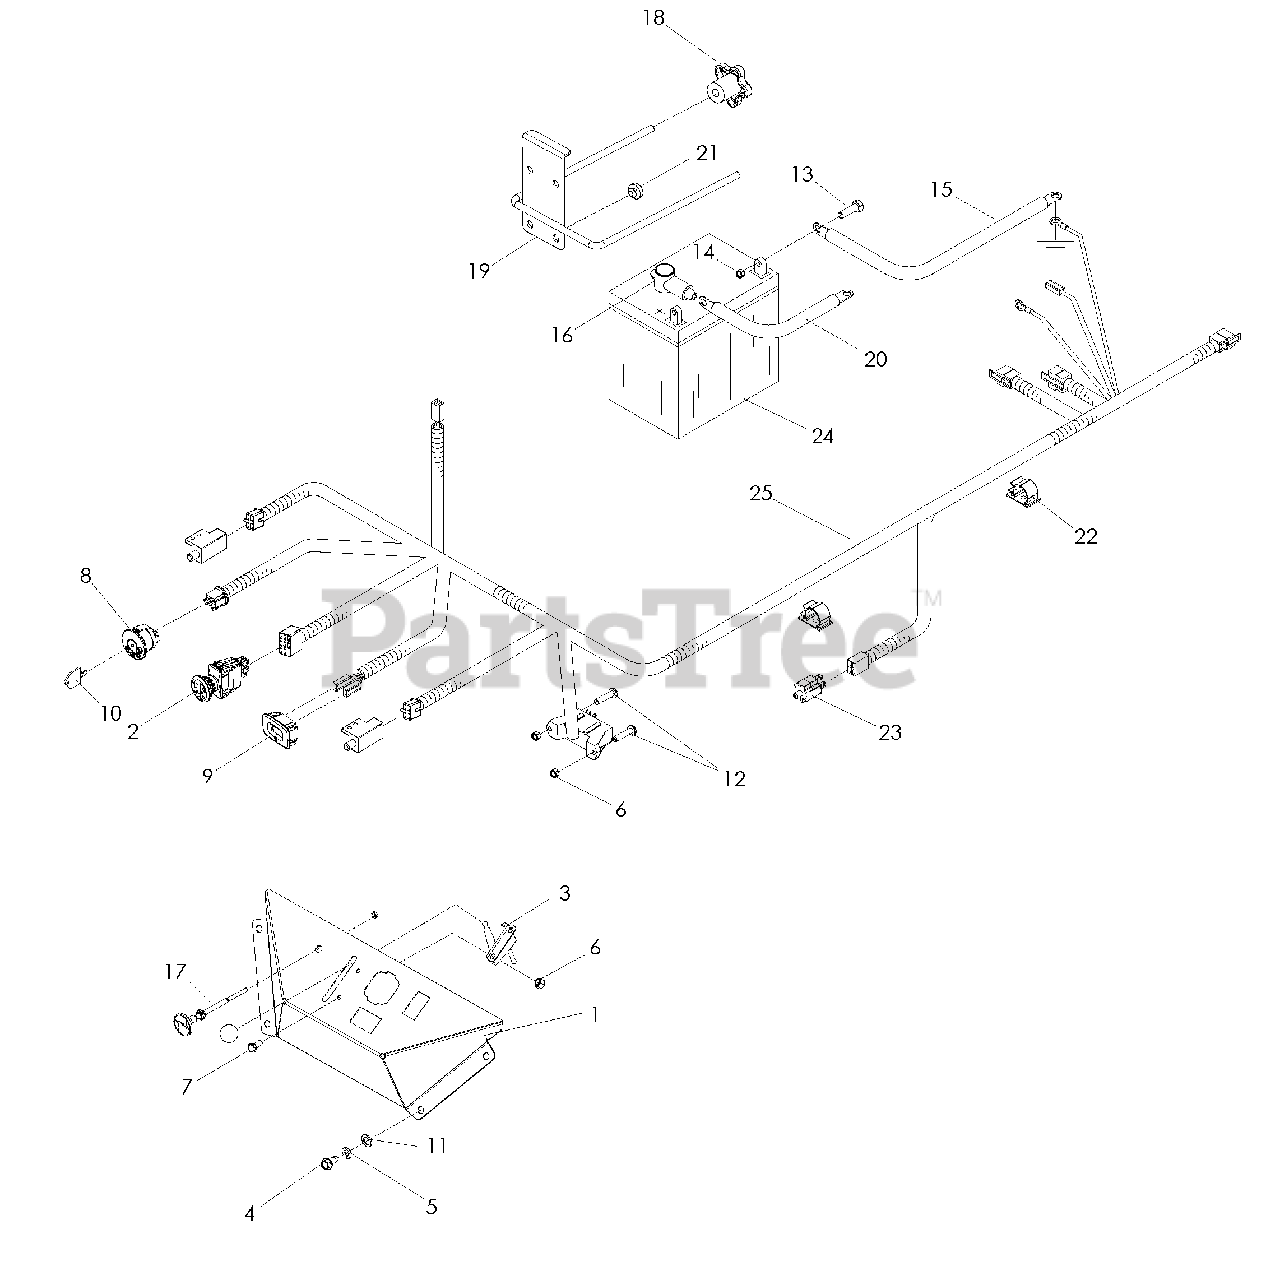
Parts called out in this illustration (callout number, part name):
2	Switch, Pto 10 Amp
3	Cable, Throttle
4	Screw 1/4-20 x 5/8
5	Washer 1/4 Split Lock
6	Nut #10-24 Hex Nyloc
7	Hcs #10-24 x 1/2
8	Switch, Ignition
9	Hour Meter
10	Key, Ignition
11	Washer 1/4 Flat
12	Screw #10-24 x 7/8 Slt Hd
13	Hcs 5/16-18 x 3/4
14	Nut 5/16-18 Hex Nyloc
15	Cable, Negative
16	Insulator, Battery
17	Control, Choke
19	Hold Down, Battery
20	Cable, Positive /
22	Wire Clip, Push-Mount
23	Switch, Brake
24	Battery, Dry
